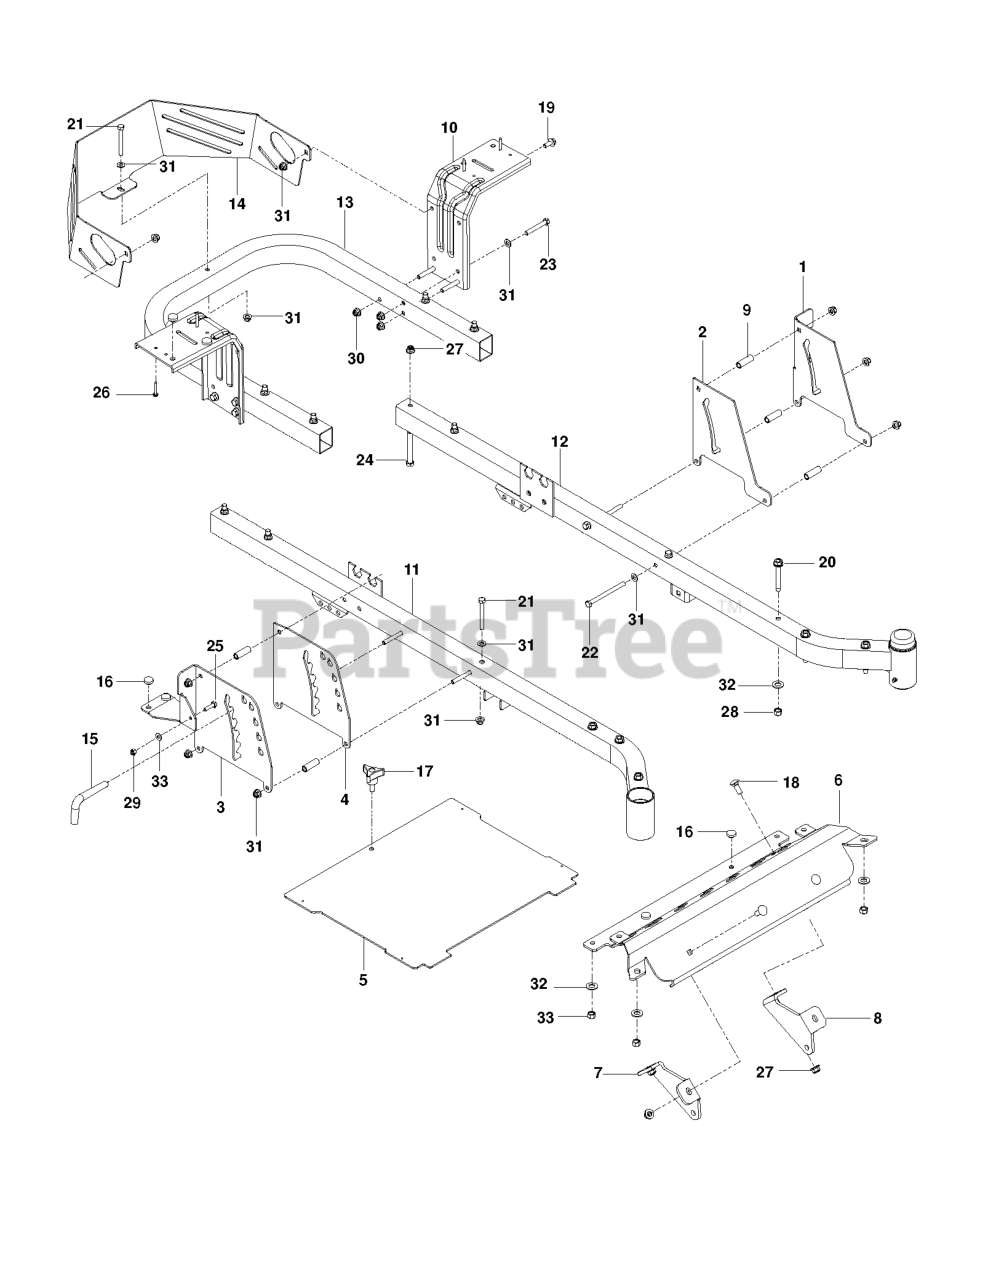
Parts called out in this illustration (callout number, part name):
1	PLATE, OUTER BRAKE, BLACK
2	PLATE, BRAKE LATCH, BLACK
3	PLATE.DECK HEIGHT.PNT.431.RZ
4	PLATE, DECK HEIGHT, BLACK
7	MOUNT.STRUT.RH.431
8	MOUNT.STRUT.LH.431
9	Spacer, .334" ID X .5 OD X 1.5
10	FENDER.SUPPORT.PNT.X431
11	FRAME.JONSERED.LT
12	FRAME.JONSERED.RT
14	GUARD.PNT.REAR.JONSERED-RED
15	Deck Height Pin, Rz
16	GROMMET, BUMPER
17	KNOB W/STUD
19	HHFS 5/16-18 X 3/4
20	HHFS 3/8-16 X 2-3/4 GR5 ZD
21	BOLT HEX**
22	BOLT 5/16-18 X 4 W/PATCH
23	BOLT NLA
24	BOLT
25	BOLT
26	SCR #10-12X1-1/2HEX WASH HD ZD
27	NUT 3/8-16 HEX FLG NYLOC ZD
28	NUT HEX 3/8-16 NYLON, THIN
29	NUT.CROWNLOCK.1/4
30	5/16-18 NYLOC FLANGE NUT
31	WASHER - 15X7.3X1.6
32	WASHER 3/8 FLAT
33	WASHER
